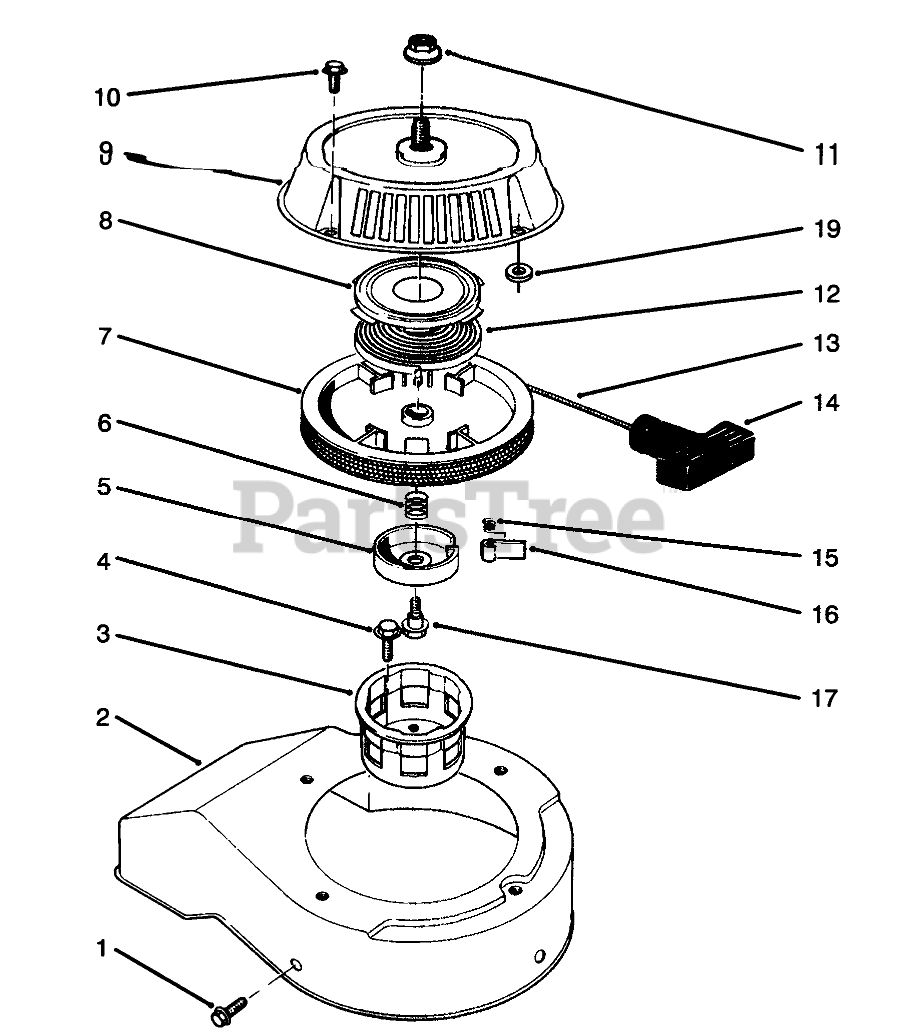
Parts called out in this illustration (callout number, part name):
2	BLOWER SHROUD
3	CUP - STARTER
4	WASHER-FLAT HD, TREATED
5	RETAINER
6	SPRING
8	Retainer-Recoil Spring
9	RECOIL CASE
10	MOUNTING SCREW
11	NUT (F/W & PPP)
12	Spring-Recoil
13	ROPE-STARTER
14	HANDLE-RECOIL
15	SPRING
19	SPACER-PLATE, PIVOT
